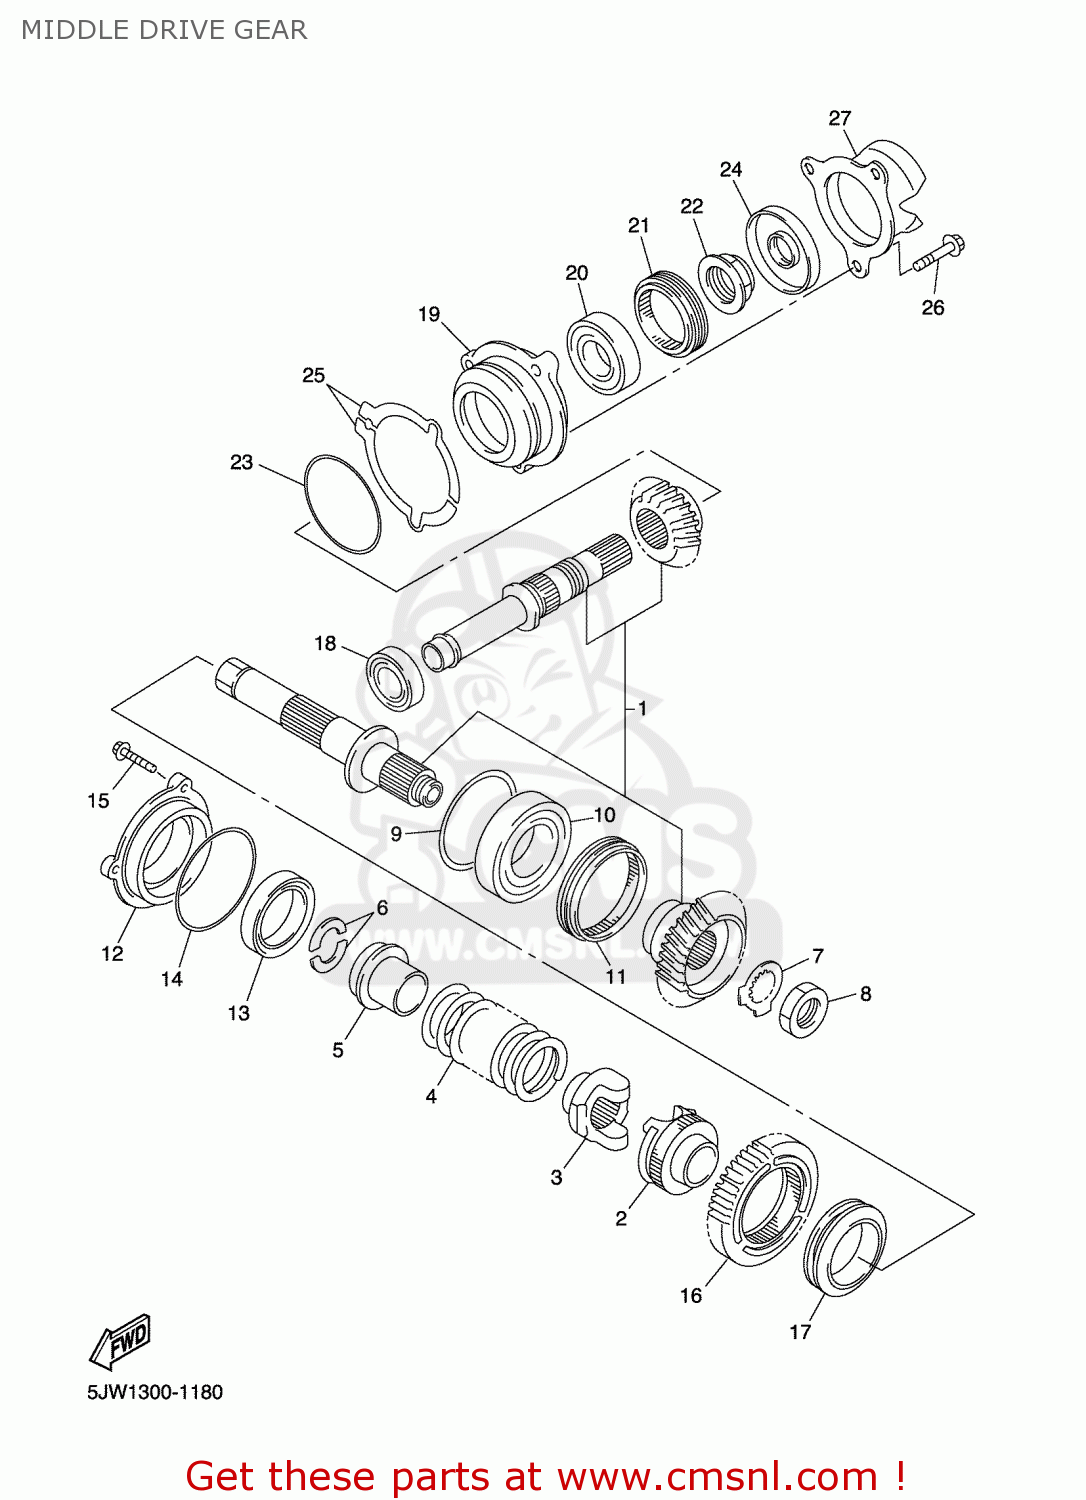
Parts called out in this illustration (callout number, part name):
01	MIDDLE GEAR COMP.
02	CAM, DRIVE
03	CAM, DRIVEN
04	SPRING, COMPRESSION (5A8)
05	HOLDER
06	WASHER(1FK)
07	WASHER, LOCK
08	NUT
09	SHIM, PINION
10	BRG,R-B 6209RSH2-C2 85MM 412G
11	NUT (4X7)
12	HOUSING, BEARING
13	BEARING
14	O-RING(4ES)
15	BOLT
16	GEAR, MIDDLE DRIVEN
17	COLLAR
18	BEARING(1FF)
19	HOUSING, BEARING
20	BEARING(1YW)
21	NUT
22	NUT
23	O-RING (722)
24	OIL SEAL
25	SHIM, PINION
26	BOLT, WASHER BASED
27	CAP, HOUSING
